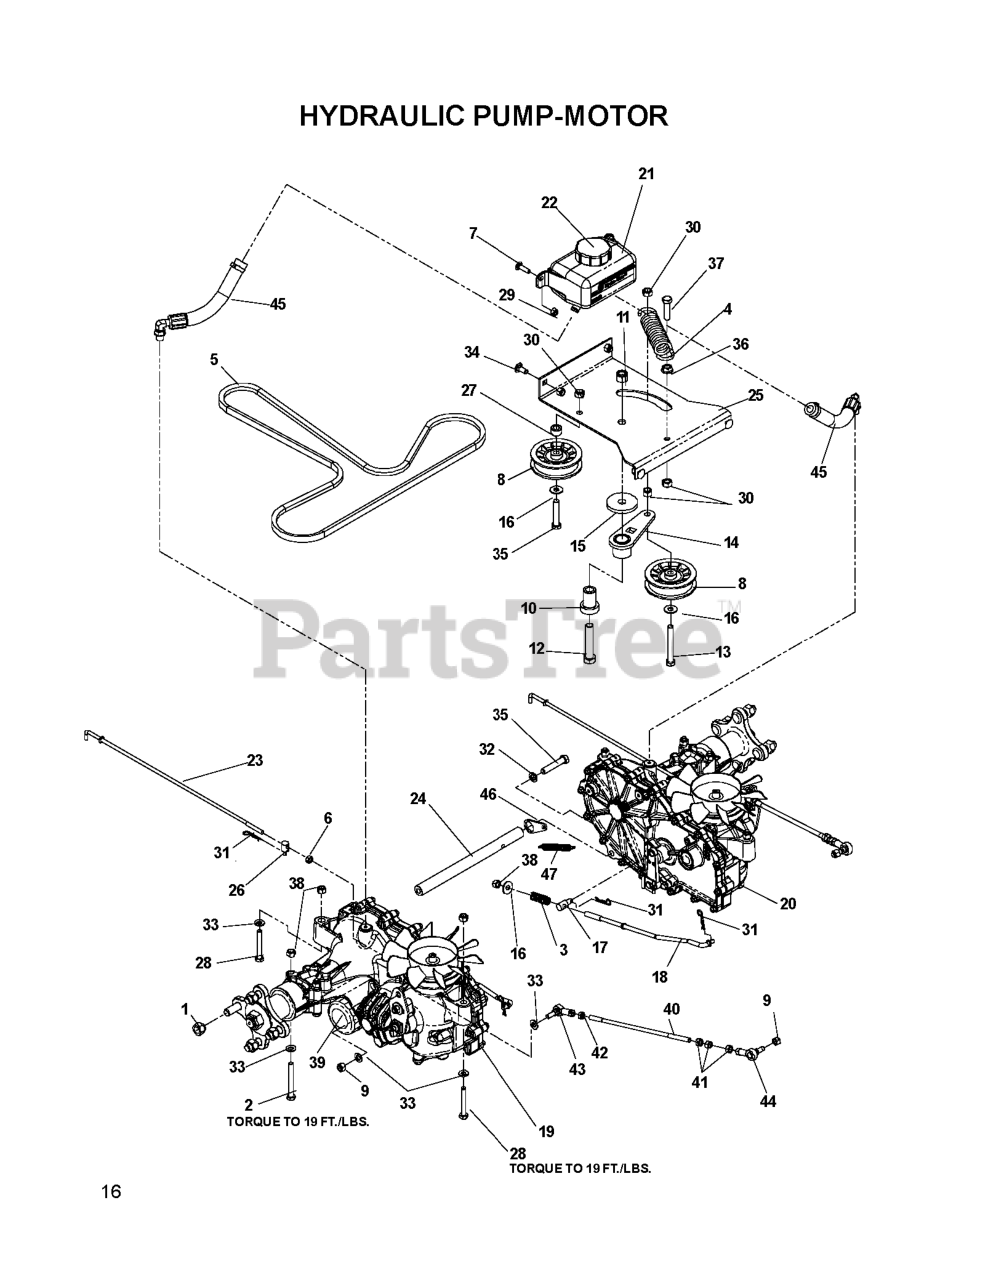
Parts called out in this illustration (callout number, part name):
1	LUG NUT 1/2F
2	HCS 5/16C X 2-3/4
5	PUMP BELT
6	NUT 1/4-28 HEX ZD
7	RHSNB, 1/4-20 X 1, GR5
8	PULLEY, IDLER RAKE & ZTR
9	NUT 5/16F NYLOC
10	IDLER SPINDLE
11	NUT 1/2-13 HEX NYLOC ZD
12	HCS 1/2C X 2 3/4
13	TAPBOLT, 3/8C X 3
14	RP.IDLER ARM WELDMENT
15	HEAVY WASHER
16	WASHER 5/16 FLAT
17	BRAKE SWIVEL
18	BRAKE LINKAGE, LOWER
19	HG_ZT2800 RIGHT SIDE
20	HG_ZT2800 LEFT SIDE
21	HG_EXPANSION TANK W/CAP 71354
22	HG_CAP 52375
23	BYPASS LINKAGE
24	2800 CROSS SUPPORT
25	IDLER PULLEY PLATE
26	SWIVEL, 1/4-28
29	NUT.1/4-20.HEX.NYLOC.ZD
30	NUT 3/8-16 NYLOC
31	HAIRPIN #2
32	SLW 3/8 STD
33	FLAT WASHER 5/16 SAE
34	BOLT 5/16C X 3/4" CARRIAGE
35	HCS 3/8C X 2
36	NUT 3/8C WHIZ
37	HCS 3/8C X 1 1/2
38	NUT 5/16 NYLOC
39	HG_FILTER, ZT4800 52114
40	DRIVE LINKAGE
42	NUT 5/16F LEFTHAND
43	SPHERICAL ROD END, LH
44	SPHERICAL ROD END, RH
46	TAB, SPRING
